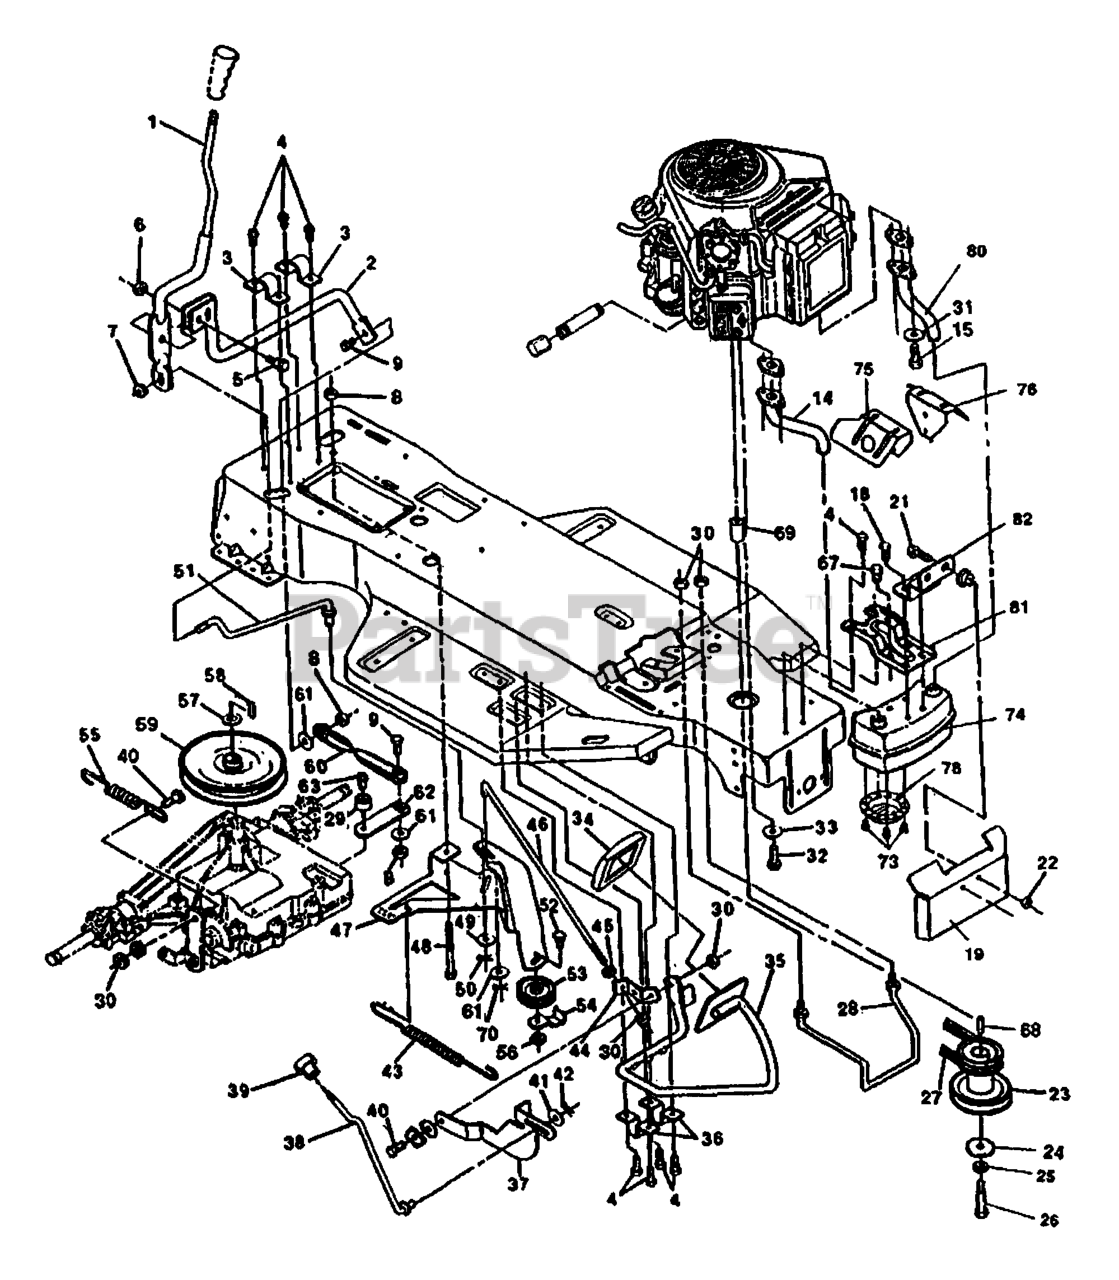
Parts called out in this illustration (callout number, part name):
4	SCREW
6	NUT
7	NUT
8	NUT
9	SCREW
14	PIPE, R.H.
15	SCREW
21	SCREW
23	PULLEY, ASSY ENG.
25	LOCK WASHER
28	BELT GUIDE
30	NUT
31	WASHER
32	SCREW
34	PAD
36	REPL BY 533 31 32-71
41	WASHER
43	SPRING
44	BRACKET NLA
45	NUT 5/16X18
49	WASHER
52	SCREW
54	HOLDER NLA
56	NUT
57	RETAINING RING
61	WASHER
63	SCREW
67	SCREW
68	KEY, SQUARE1/4
73	SCREW
80	PIPE, L.H.
82	BRACKET
